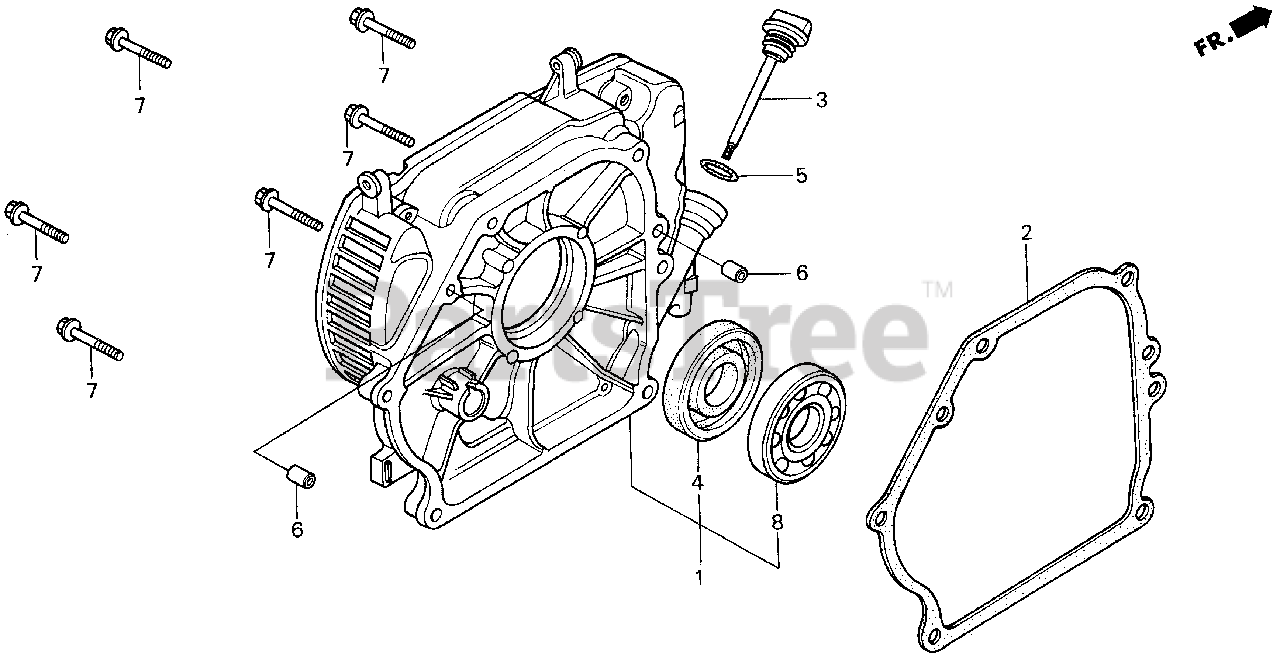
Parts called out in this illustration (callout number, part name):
1	COVER ASSY., CRANKCASE
2	GASKET, CASE COVER
2	GASKET, CASE COVER (NON-ASBESTOS)
3	CAP, OIL FILLER
4	OIL SEAL (25X41X6)
5	O-RING (16MM)
6	PIN A, DOWEL (8X14)
7	BOLT, FLANGE (8X32)
8	BEARING, RADIAL BALL (6205)
